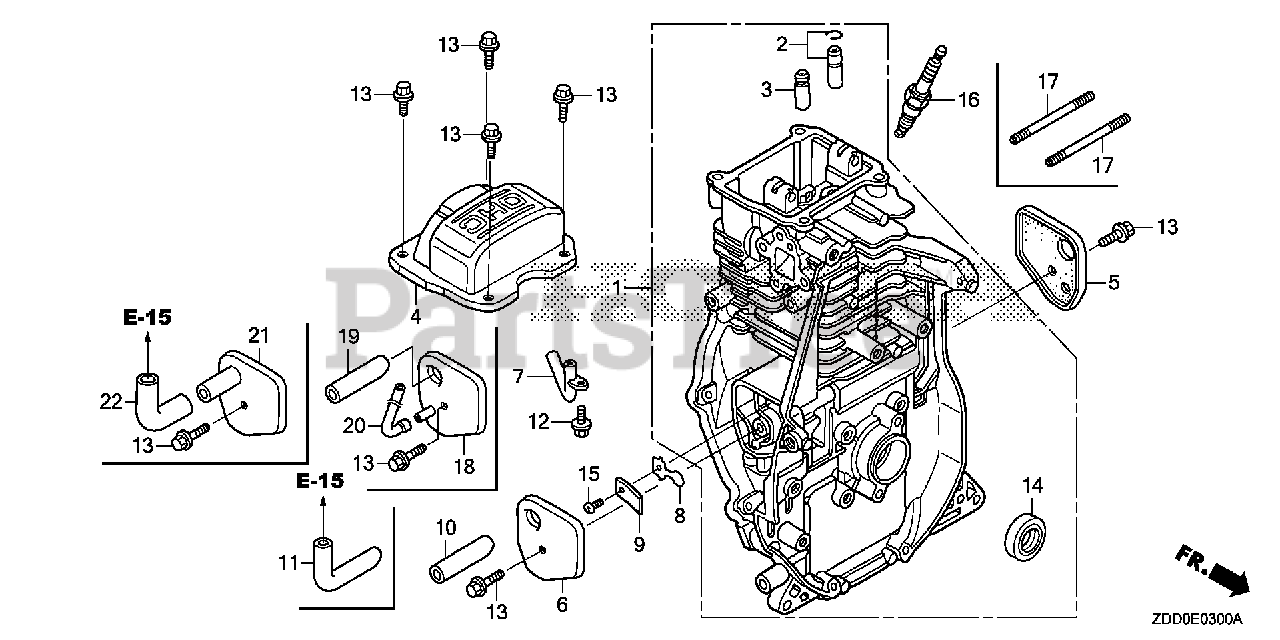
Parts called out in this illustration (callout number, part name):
1	CYLINDER ASSY.
2	GUIDE ASSY., EX. VALVE (OVER SIZE)
3	GUIDE, VALVE (OVER SIZE)
4	COVER, HEAD
5	COVER A, BREATHER
6	COVER B, BREATHER
8	VALVE, OIL OUTLET
9	PLATE, STOPPER
10	TUBE, BREATHER
13	BOLT, FLANGE (6X14)
14	OIL SEAL (20X32X6)
15	SCREW, PAN (3X5)
16	SPARK PLUG (U16FSR-UB) (DENSO)
16	SPARK PLUG (CR5HSB)
